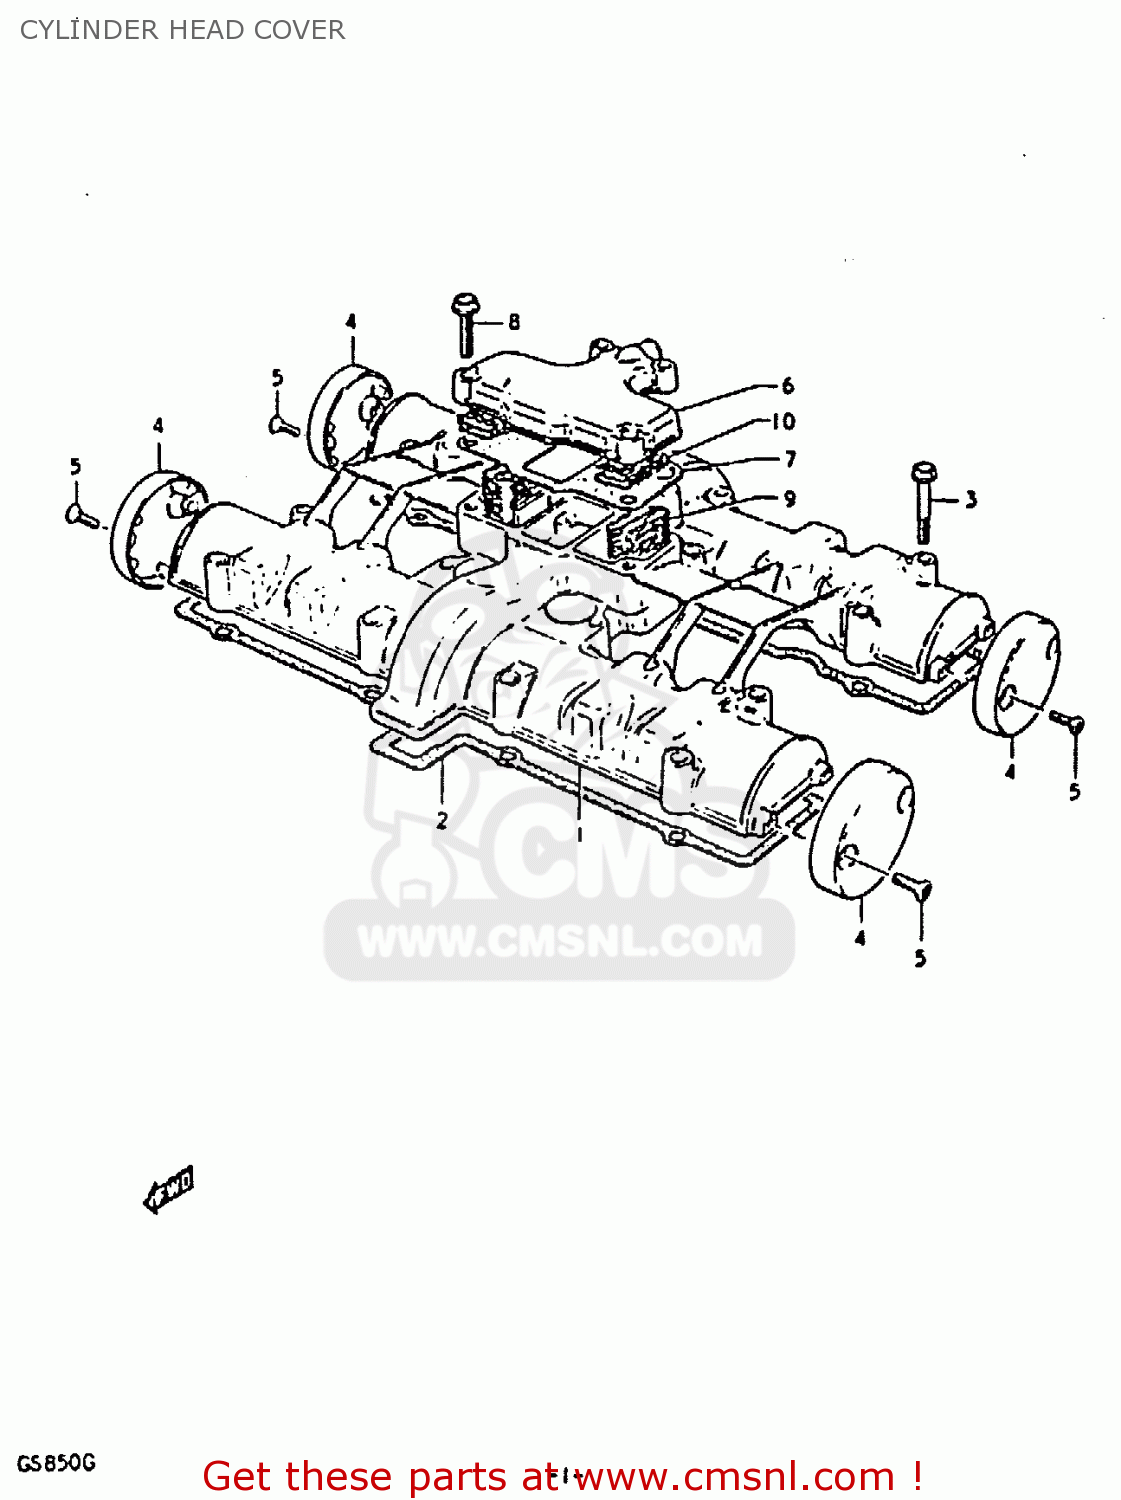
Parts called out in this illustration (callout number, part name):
1	COVER,CYLINDER HEAD
2	GASKET,CYLINDER HEAD COVER (MCA)
3	BOLT
4	CAP,CYLINDER HEAD COVER
5	SCREW
6	COVER,BREATHER
7	GASKET (MCA)
8	BOLT
9	COVER,BREATHER
10	SEPARATOR,OIL BREATHER
